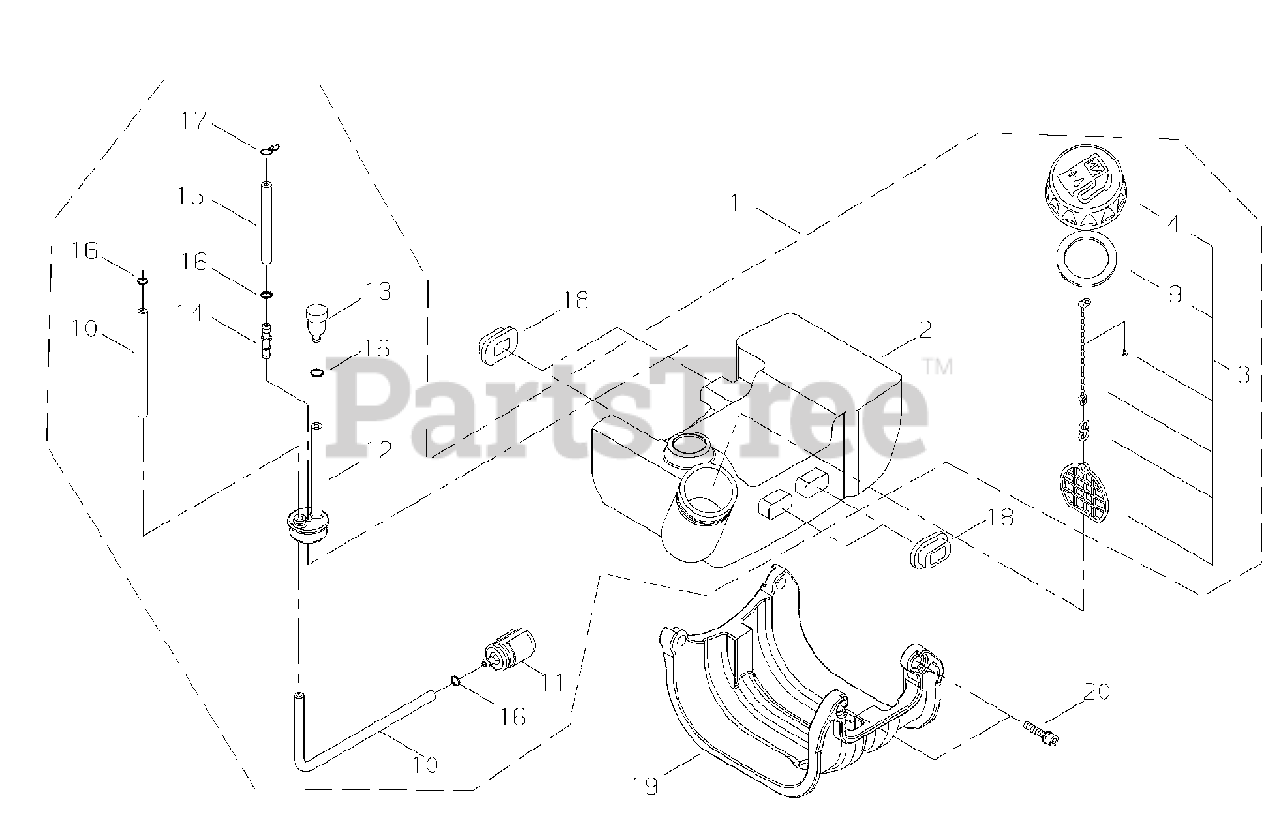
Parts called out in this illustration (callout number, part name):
2	TANK, FUEL
3	CAP ASSY, FUEL
4	CAP, FUEL
9	GASKET, FUEL CAP
10	PIPE, FUEL
11	FILTER, FUEL 125-528
12	GROMMET, FUEL W/VENT PIPE
13	VENT ASSY
14	CONNECTOR, PIPE
15	PIPE, FUEL RETURN
16	CLIP Ø6
17	CLIP, SPRING Ø5.2
18	CUSHION, FUEL TANK
19	GUARD, PLASTIC FUEL TANK
20	BOLT M5×20
